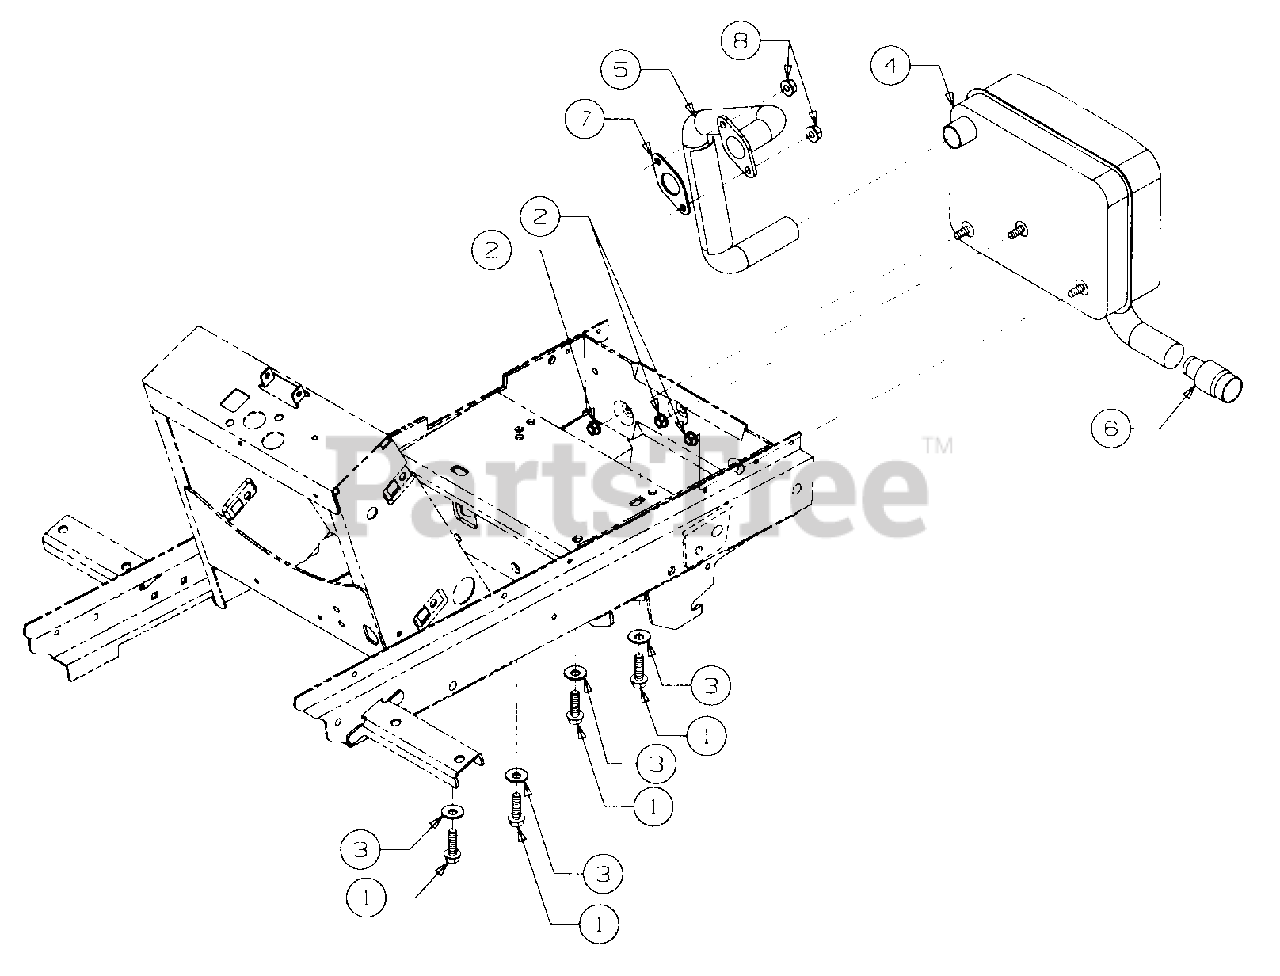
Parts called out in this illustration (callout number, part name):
1	Bolt, Engine Mtg, 3/8-16 x 1.25 Lg
2	Nut, Hex Flange Top Lock, 5/16-18
3	Washer, Bell, .380 x .88 x .062 Thk
4	Muffler Assembly
5	Tube, Exhaust
6	Arrestor, Spark
7	Gasket, Exhaust
8	Nut, Hex Flange
